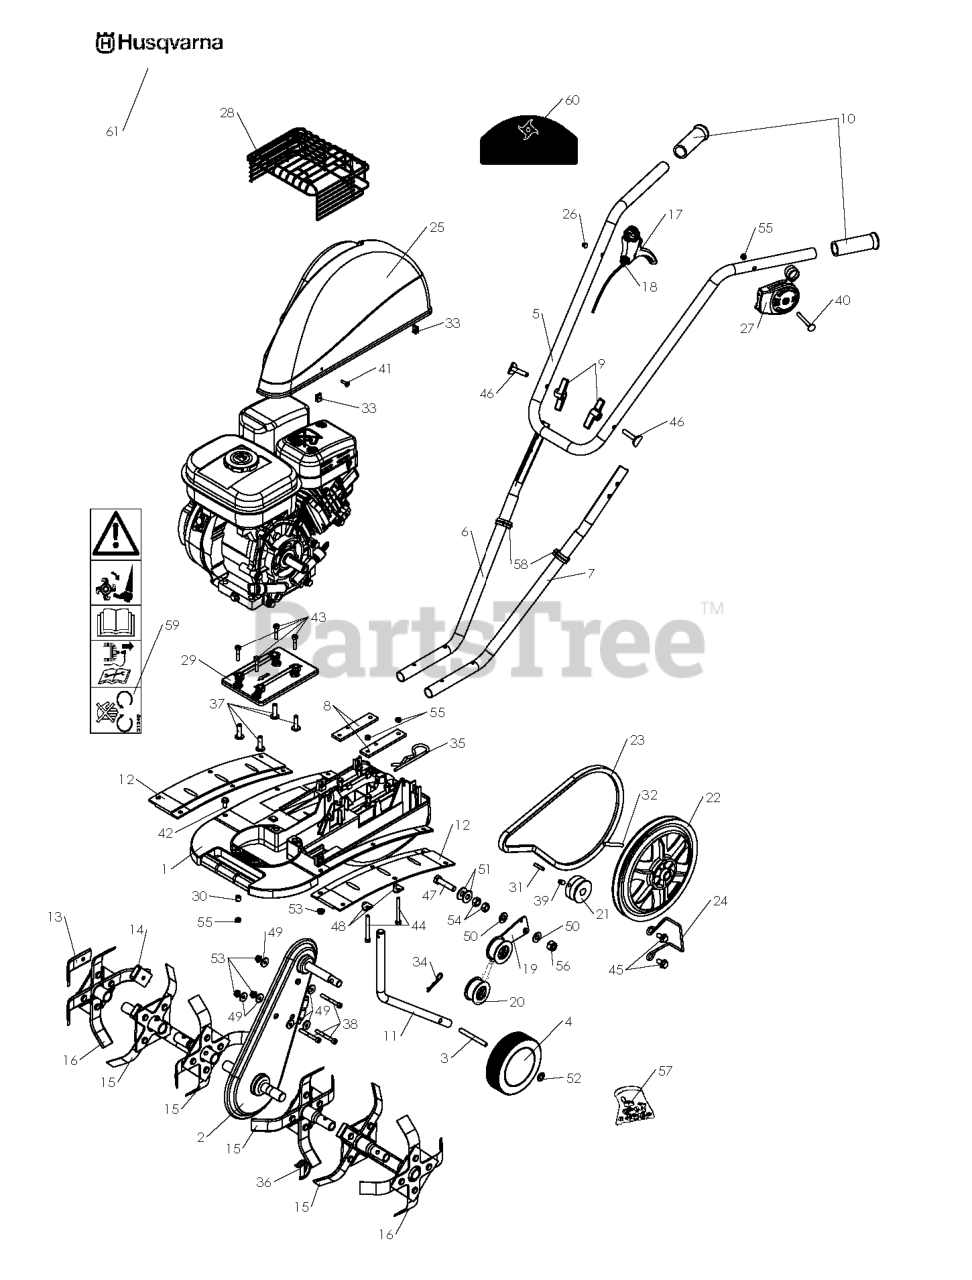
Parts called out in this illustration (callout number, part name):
18	CABLE CLUTCH
34	COTTER PIN
43	SCREW 0300010603
50	WASHER
55	Blocking nut M 6 Z
